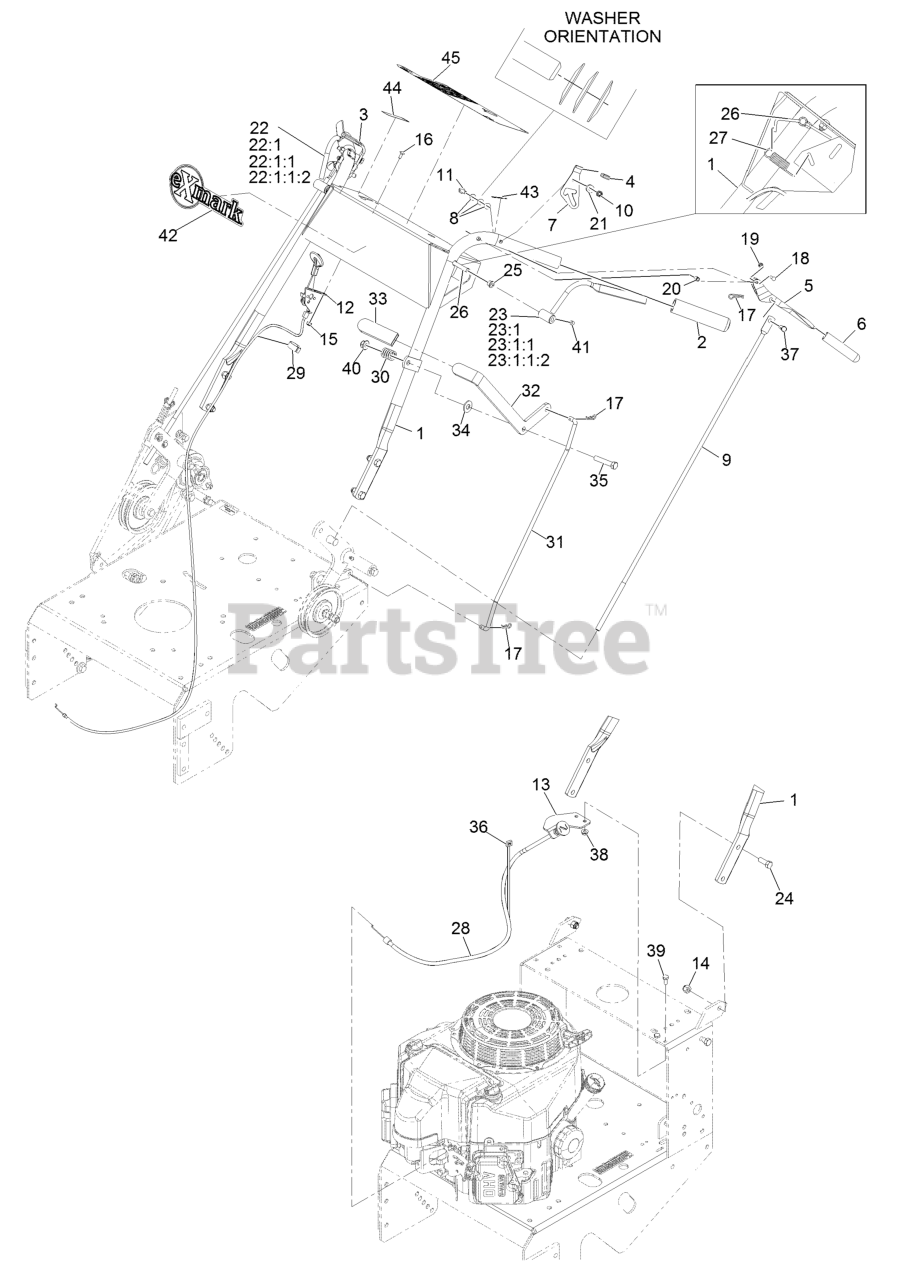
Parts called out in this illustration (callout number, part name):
1	Wld,Handle Metro
1	KIT,HANDLE W/DECALS METRO
2	GRIP-FOAM
4	GRIP-LATCH
5	DRIVE LEVER ASM
6	GRIP-LEVER, DRIVE
8	WASHER-SPRING
9	LINKAGE-WHEEL, DRIVE
10	NUT-LOCK, NI
11	SCREW-HH
12	CONTROL, THROTTLE
13	BRACKET-CABLE, CHOKE
14	NUT-LOCK, NI
15	NUT-LOCK, NI
16	BOLT-CARR
17	PIN-COTTER
18	PIN-LEVER, DRIVE
19	NUT-PUSH
20	PIN-ROLL
22	LEVER-RH
22:1	Lever
22:1:1	ASM,Hub/Setscrew
22:1:1:2	SCREW-SET
23	LEVER-LH
23:1	Lever
23:1:1	ASM,Hub/Setscrew
23:1:1:2	SCREW-SET
24	SCREW-HH
25	BUSHING-NYLON
26	WLD,ROD OPC
27	SPRING-EXTENSION
28	CABLE-CHOKE
29	CLIP-CABLE
30	SPRING-COMPRESSION
31	LINKAGE-BLADE, UPPER
32	LEVER ASM
33	GRIP-LEVER
34	WASHER-FLAT
35	SCREW-HH
36	TIE-PLASTIC
37	PIN-CLEVIS
39	SCREW-HH
40	NUT-HF, NI
41	SCREW-SET
42	DECAL, EXMARK LOGO
43	DECAL-NEUTRAL BRAKE
44	DECAL-THROTTLE
45	DECAL-CONSOLE METRO PG
